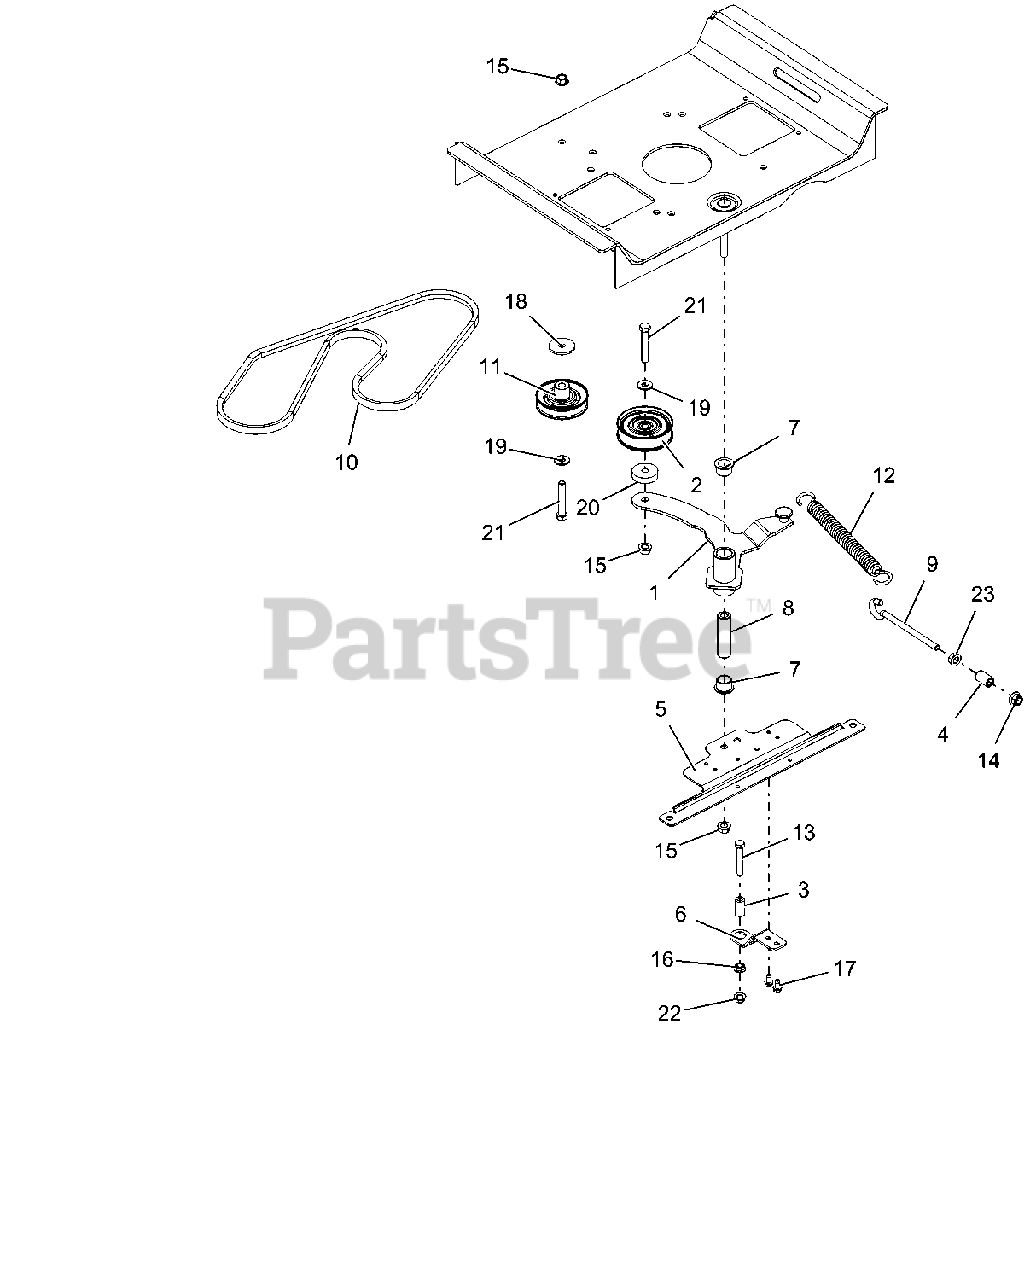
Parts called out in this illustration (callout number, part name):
1	WLDMT,GRD DRIVE IDLER ARM-LGR
2	IDLER, FLAT - 3.05" X .75"
3	SPACER, RUBBER 5/16 IDX1.0 LG
4	SPACER, .375X.625X.970 (PM)
5	BRKT, DRIVE IDLER MOUNTING
6	BRKT, CLUTCH STOP (XL)
7	BSHG-FLG 0.75X0.875X.625X1.125
8	BUSHING, SLEEVE .38X.750X2.78
9	BOLT,.38-16 X 4.25-.62 DIA EYE
10	V-BELT, A-RAW EDGE
11	ASM, 3.00" V IDLER
12	SPRING, EXTENSION
13	@BLT-HEX .31-18X2.00 GR5 YWZC
14	@NUT-LK-NYL-FLG .38-16 YWZC
15	@NUT-LK-TOP-FLG .38-16 YWZC
16	@NUT-SPNLK-FLG .312-18 YWZC
17	SCR-TAP .25-20X.50 HWH TR YWZ
18	WSHR-FL-STL .380X1.50X.125YWZC
19	@WSHR-FL-STL.38X.875X.083 YWZC
20	SPACER, .39 X 1.50 X .380
21	@BLT-HEX .38-16X2.25 GR5 YWZC
22	@NUT-LK-TOP-FLG .31-18 YWZC
23	@NUT-SPNLK-FLG .375-16 YWZC
